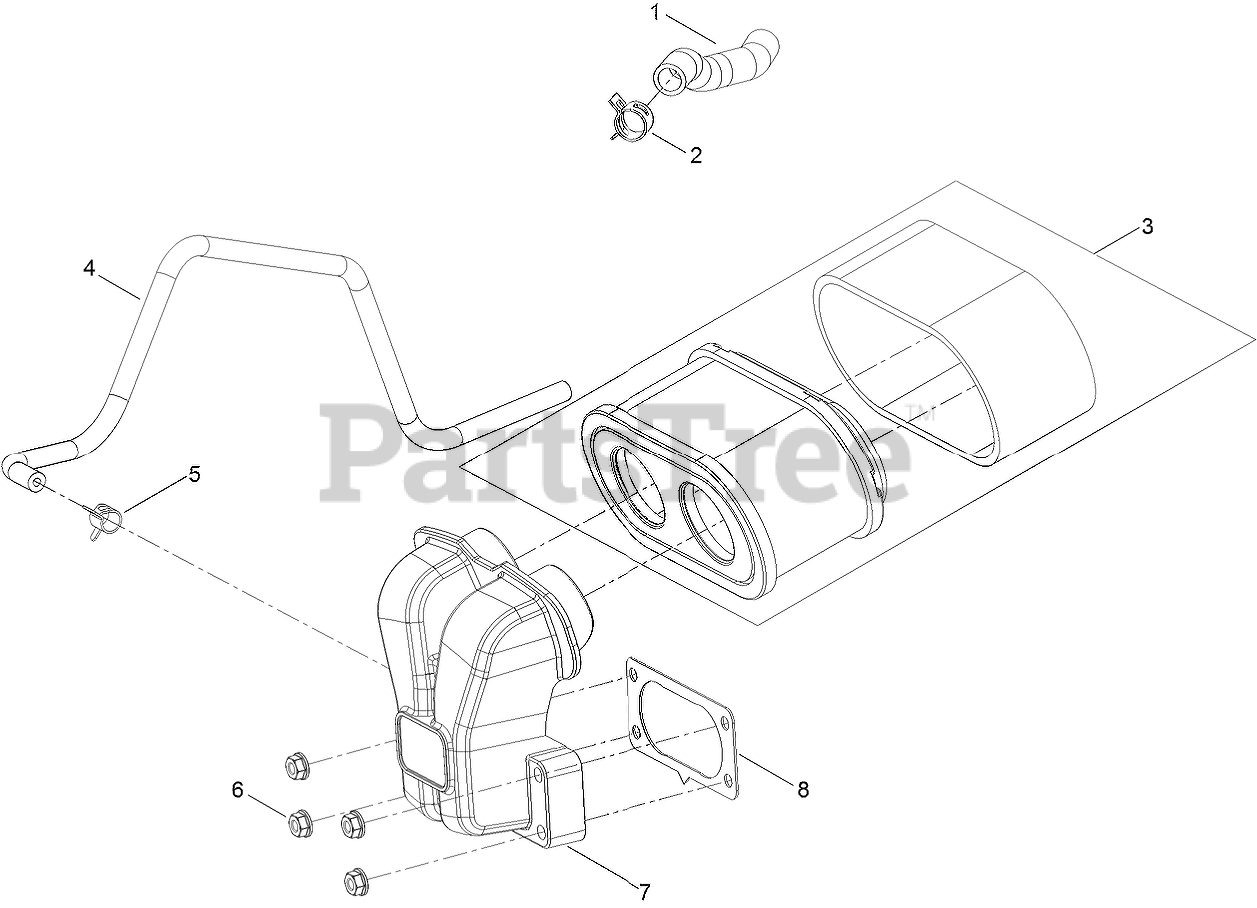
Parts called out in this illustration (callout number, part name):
1	TUBE-BREATHER
2	CLAMP-HOSE
3	FILTER-AIR, COMPLETE
4	HOSE-FUEL
5	CLAMP-HOSE
6	NUT-FLANGE
7	MANIFOLD-FILTER, AIR
8	GASKET-CARBURETOR
